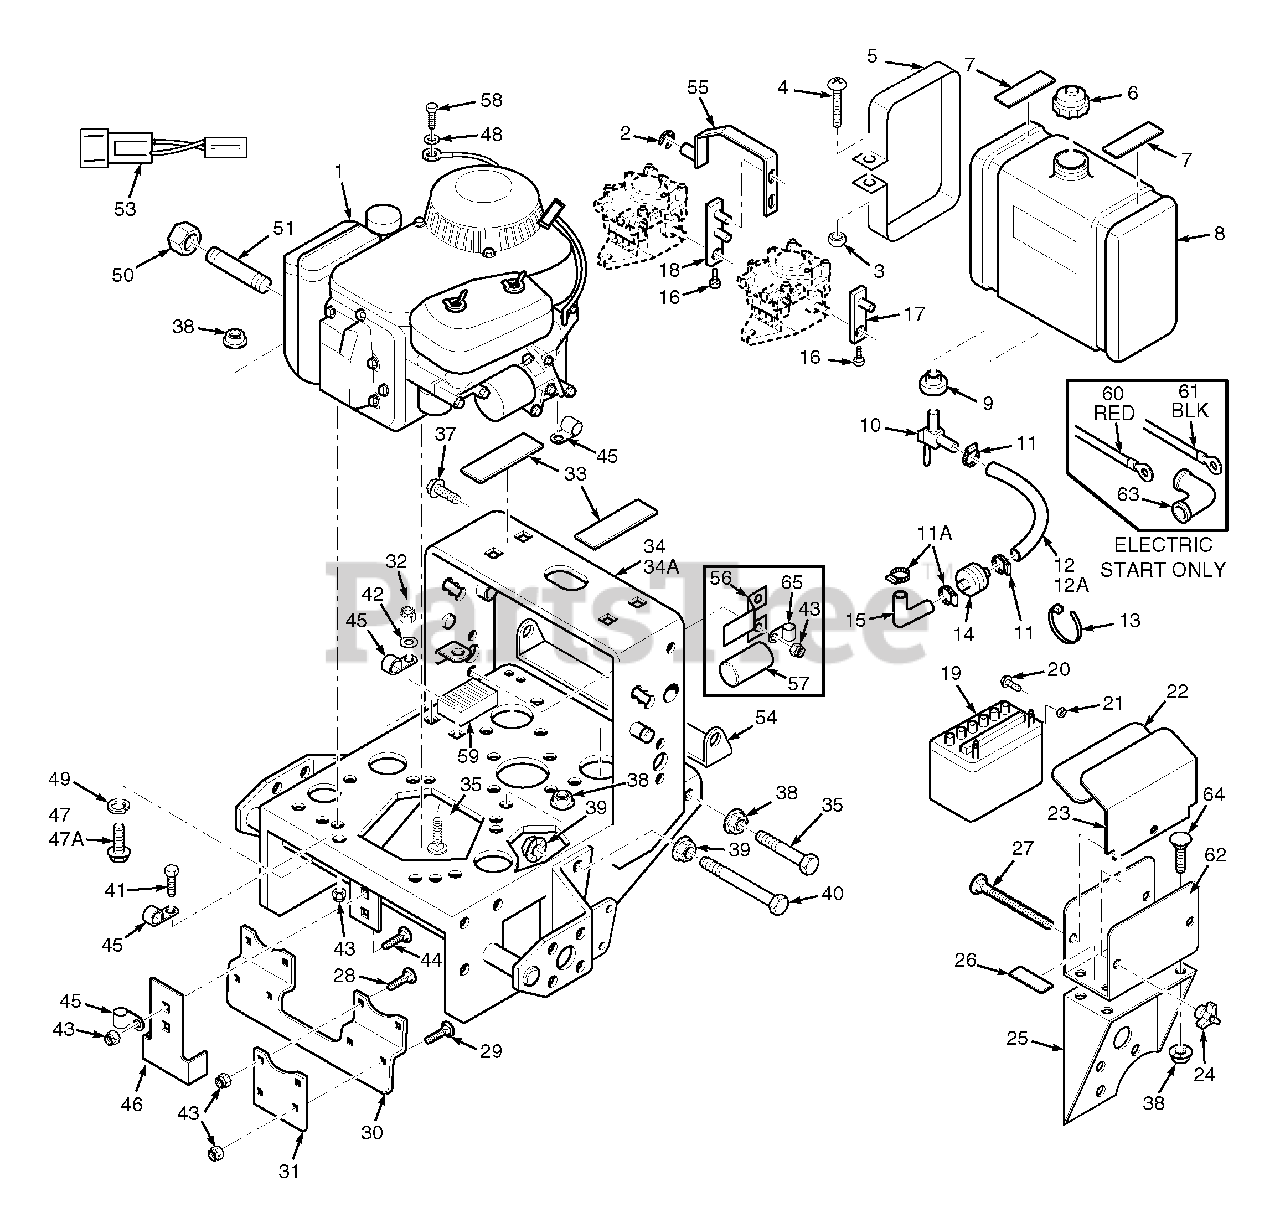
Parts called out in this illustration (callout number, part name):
1	Engine 17KA Kawasaki
2	Retaining Ring, 1/2" Ext. "E"
3	Hex Nut, 1/4-20
4	Screw, 1/4-20 x 2" Rnd. Hd. Phil.
5	Strap, Fuel Tank
6	Cap, Fuel Tank
7	Pad, Rubber-Fuel Tank - Upper
8	Fuel Tank Assy.
9	Bushing
10	Valve, Fuel Shut-off
11	Clamp, Fuel Hose
11A	Clamp, Fuel Hose,
12	Fuel Hose, 1/4 ID x 20" KA
12A	Fuel Hose, 1/4 ID x 23"
13	Cable Tie
14	Fuel Filter
16	Capscrew, #10-32 x 1 Soc. Hd.
17	Lever Assy., Pump Control -LH
18	Lever Assy., Pump Control -RH
19	Battery
22	Pad
23	Battery Cover
25	Battery Support
26	Pad, Rubber
27	Bolt, 1/4-20 x 6" Carriage
28	Carriage Bolt, 5/16-18 x 2"
29	Carriage Bolt, 5/16-18 x 1"
30	Stiffener
31	Plate, Backing
32	Nut, 1/4-20 Elastic Stop
33	Pad, Rubber-Fuel Tank, Lower
34	Engine Deck, 16" Wide, W/Decls.
34A	Engine Deck, 20" Wide, W/Decls.
35	Bolt,1/4-20 x 1-1/4" Hex Head
36	Nut, 1/4-20 Serrated Flange
37	Capscr., 5/16-18 x 1.25 Sr. Flg.
38	Nut, 5/16-18 Serr. Flange
39	Nut, 3/8-16 Serr. Flange
40	Bolt, 3/8-16 x 2-3/4" Hex Head
41	Hex Head Bolt, 5/16-18 x .75"
42	Flat Washer 1/4"
43	Nut, 5/16-18 Elastic Stop
44	Carrage Bolt, 5/16-18 x 1"
46	Clutch Bracket
47	Capscr, 5/16-18 x 1.50" Sr. Flg.
47A	Metric HH Bolt, M8-1.25 x M30
48	Lock Washer, 5/16 Int. Tooth
50	Pipe Cap
51	Pipe, 4.75" Nipple
53	Wire Hrns. Adapter, 17KA
54	Pulley Guard, 20" Frame
55	Shaft Weldment, RH Pump Cntl.
56	Bracket, Capacitor
57	Condenser
58	Metric H H Bolt, 8-1.25 x 10
59	Regulator
60	Battery Cable, 31.5" Red
61	Battery Cable, 31.5 Black
62	Battery Box
63	Rubber Boot
65	Cable Clamp, .75 ID
